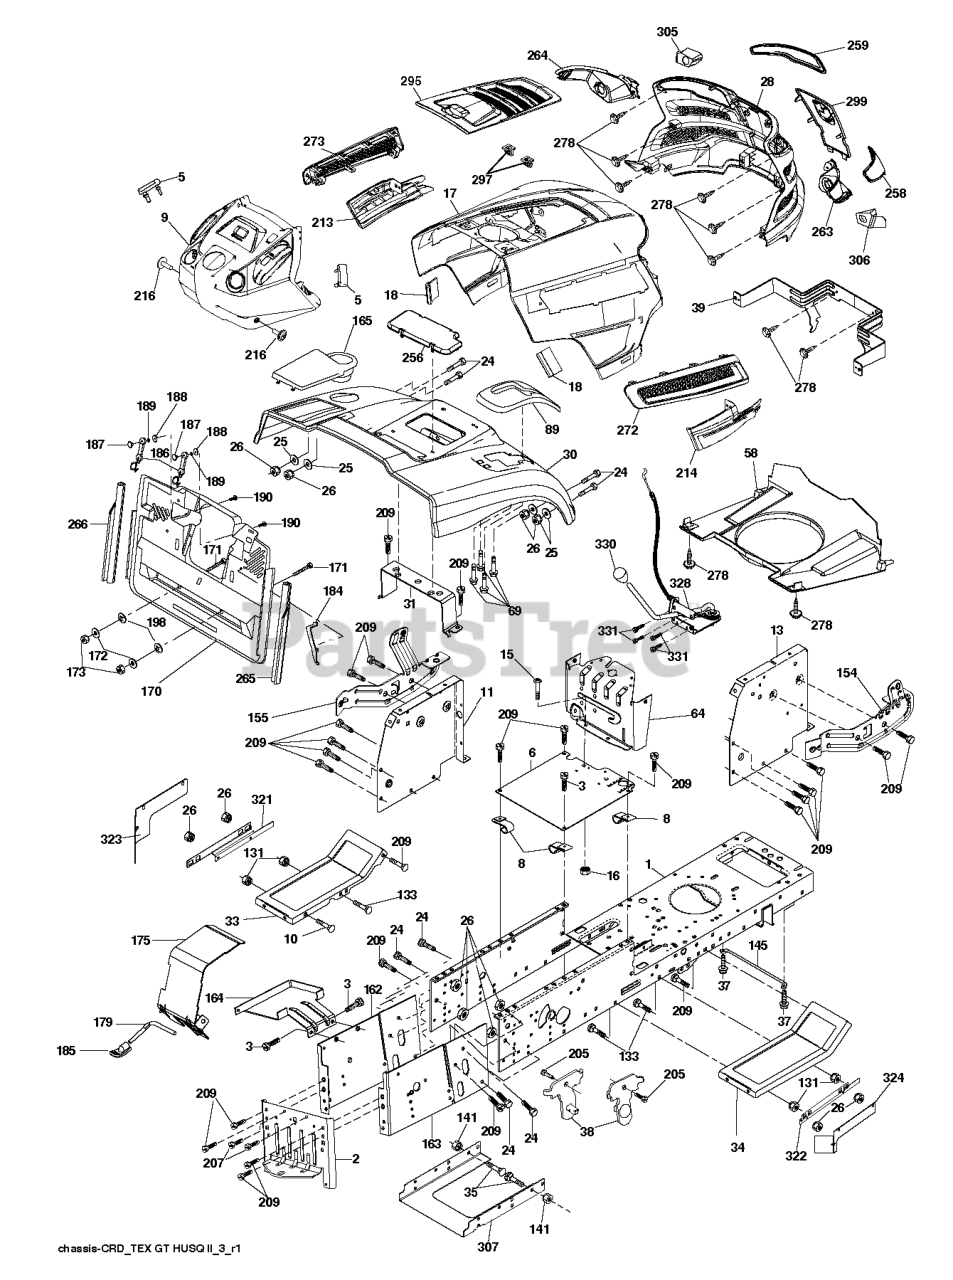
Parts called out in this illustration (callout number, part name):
2	DRAWBAR
3	SCREW 3/8-16X3/4
5	BUMPER DASH
6	PLATE
8	CLIP,INSULATOR
10	BOLT.3/8-14X1.25
11	PANEL DASH LH
13	PANEL DASH RH
15	Screw, Machine, Truss Head 5/16-18 UNC x 3/4
16	NUT
17	HOOD.ASM.HUSQVARNA.GT.TEX.ORAN
18	BUMPER.HOOD.TEX.HUSQVARNA
25	WASHER
26	NUT
28	GRILLE.SUBSTRATE.2011.
30	CONSOLE.CRD.AUTO.GRY
31	BRACKET SUPPORT FENDER
33	FOOTREST PNT LH
34	FOOTREST PNT RH
37	Screw 5/16-18 x 1/2 Hex, Self Tapping 5/16-18 x 1/2
38	BRACKET ASM PIVOT MOWER REAR
39	BRACKET.PIVOT.HOOD.GT.HUSQ.II
58	AIR.DUCT.GTV.BLACK
69	SCREW.HI-LO.CONSOLE
89	CONSOLE.CRD.AUTO.GREY.2005
131	NUT.HEX.3/8-16UNC
133	BOLT D
141	NUT LOCK FLG 3/8-16 UNC
145	ROD.PIVOT.HOOD
162	BRACKET
163	BRACKET EXTEN CHASSIS RH CRD
165	COVER.BATTERY.BGGR.ELE
172	WASHER
175	DOOR TRAP
179	ROD PIVOT FBI
184	BRACKET.ACTUATOR.BAGGER.SRD
186	LATCH ASSY
187	WELDNUT
189	LOCKWASHER #10
190	SCREW
207	SCREW, 5/16-18 X 1/2
209	SCREW, 3/8-16X3/4
213	SIDE.TRIM.LH.GT.HUSQ.II.GRAY
214	SIDE.TRIM.RH.GT.HUSQ.II
216	SCREW 14-20 X 5/8
256	COVER FENDER CRD
258	LENS.HEADLIGHT.RH.GTII.2011
259	LENS.HEADLIGHT.LH.GTII.2011
263	BEZEL LIGHT.RH.GT.II.MYLAR
264	BEZEL LIGHT.LH.GT.II.MYLAR
265	SEALING
266	SEALING
272	VENT.SIDE.RH.GT.HUSQ.II.
273	VENT.SIDE.LH.GT.HUSQ.II.498
278	SCREW.#10 X 0.750.BOS
297	CLIP.RETAINER.TINNER.
299	APPLIQUE.SUBASM.GT.HUSQ.II
305	INSERT.REFLECTIVE.LH.HUSQ.GTII
306	INSERT.REFLECTIVE.RH.HUSQ.GTII
321	SHIELD INNER LEFT
322	SHIELD INNER RIGHT
323	PLATE LEFT
324	PLATE RIGHT
330	SIDE.TRIM.LH.GT.HUSQ.II.GRAY
331	SCREW.#10-24X5/8.RN.QU
